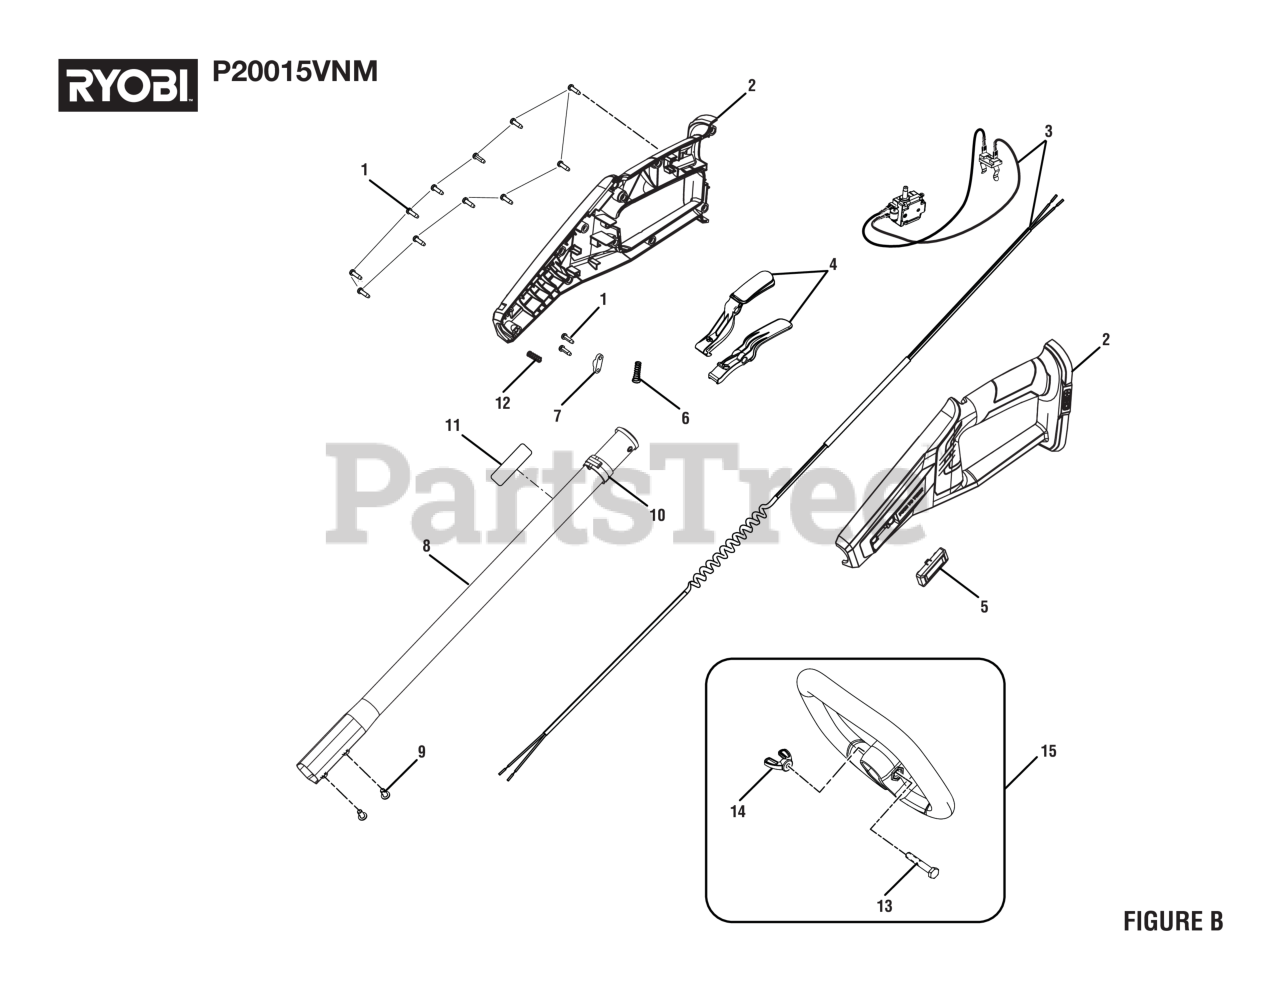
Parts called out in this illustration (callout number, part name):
1	Screw (M4 x 14 mm, T15 Torx Pan Hd.))
2	Handle Housing Assembly w/Label
3	Switch, Contact Plate Assembly and Wire Harness
4	Switch Trigger and Lock-Out Assembly
5	Rotate Button
6	Compression Spring (Trigger)
7	Cord Clamp
8	Upper Tube Assembly (Inc. Key No. 11)
9	Screw w/Lock Washer (M5 x 8 mm, Pan Hd.)
10	Lock Ring
11	Warning Icon Label
13	Bolt (1/4-20 x 45 mm, Cap Hex Hd.)
14	Wing Nut (1/4-20, Plastic)
15	Auxiliary Handle Assembly
